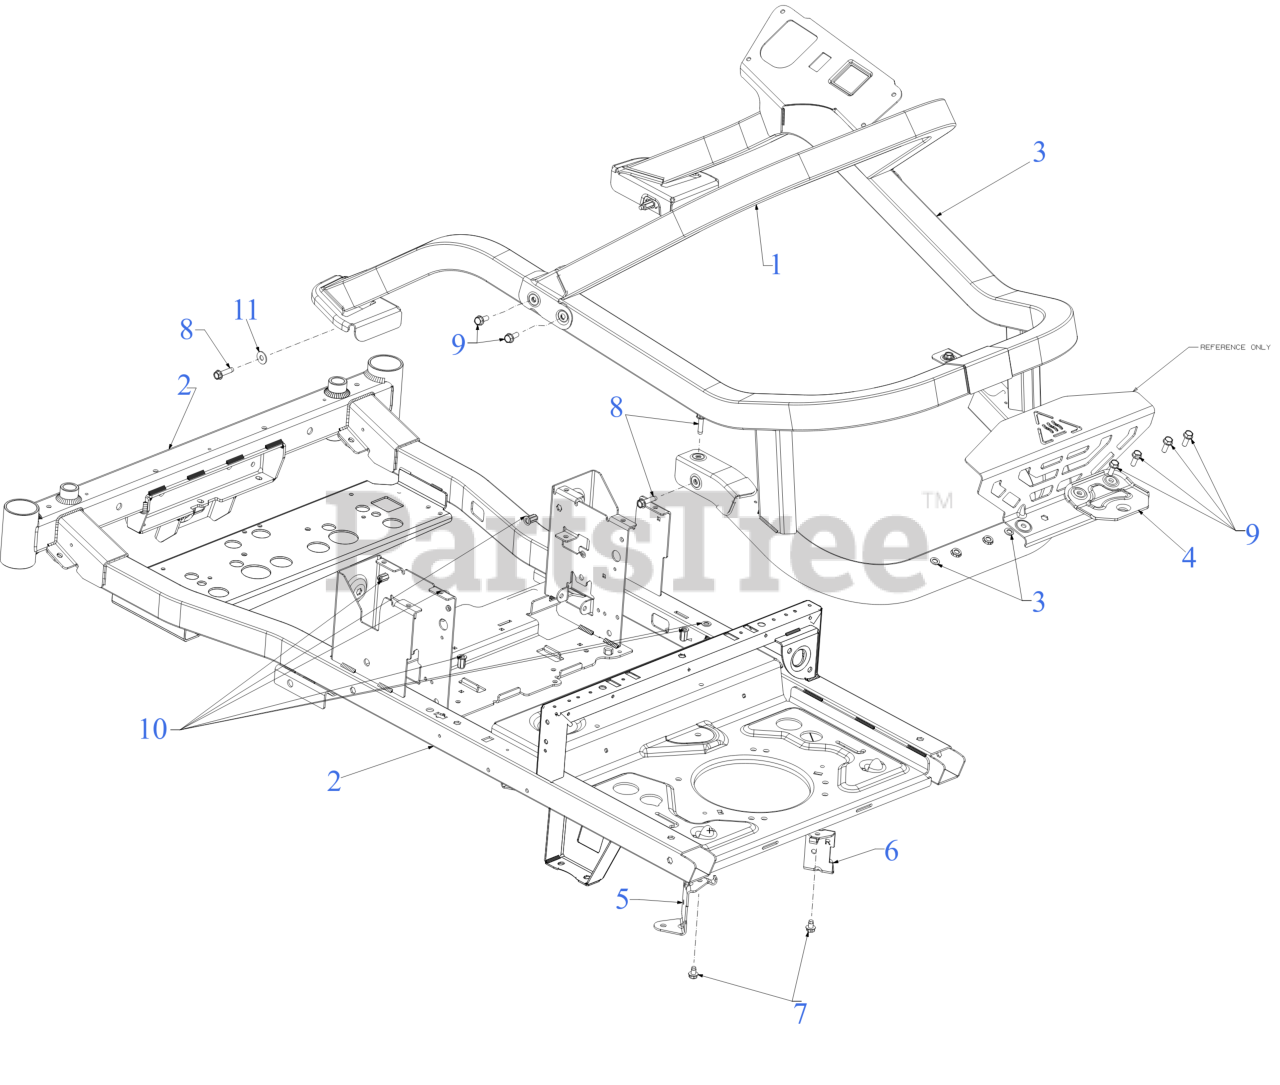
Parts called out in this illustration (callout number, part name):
1	UPPER FRAME HOOP
2	FRAME
3	FRAME (UPPER)
4	HITCH PLATE
5	TRANSMISSON MOUNT SUPPORT (LH)
6	TRANSMISSON MOUNT SUPPORT (RH)
7	SCREW 5/16-18 x .500
8	SCREW 5/16-18 x 1.25
9	SCREW 5/16-18 x .875 GR5
10	NUT RIVET 5/16-18
11	FLAT WASHER
